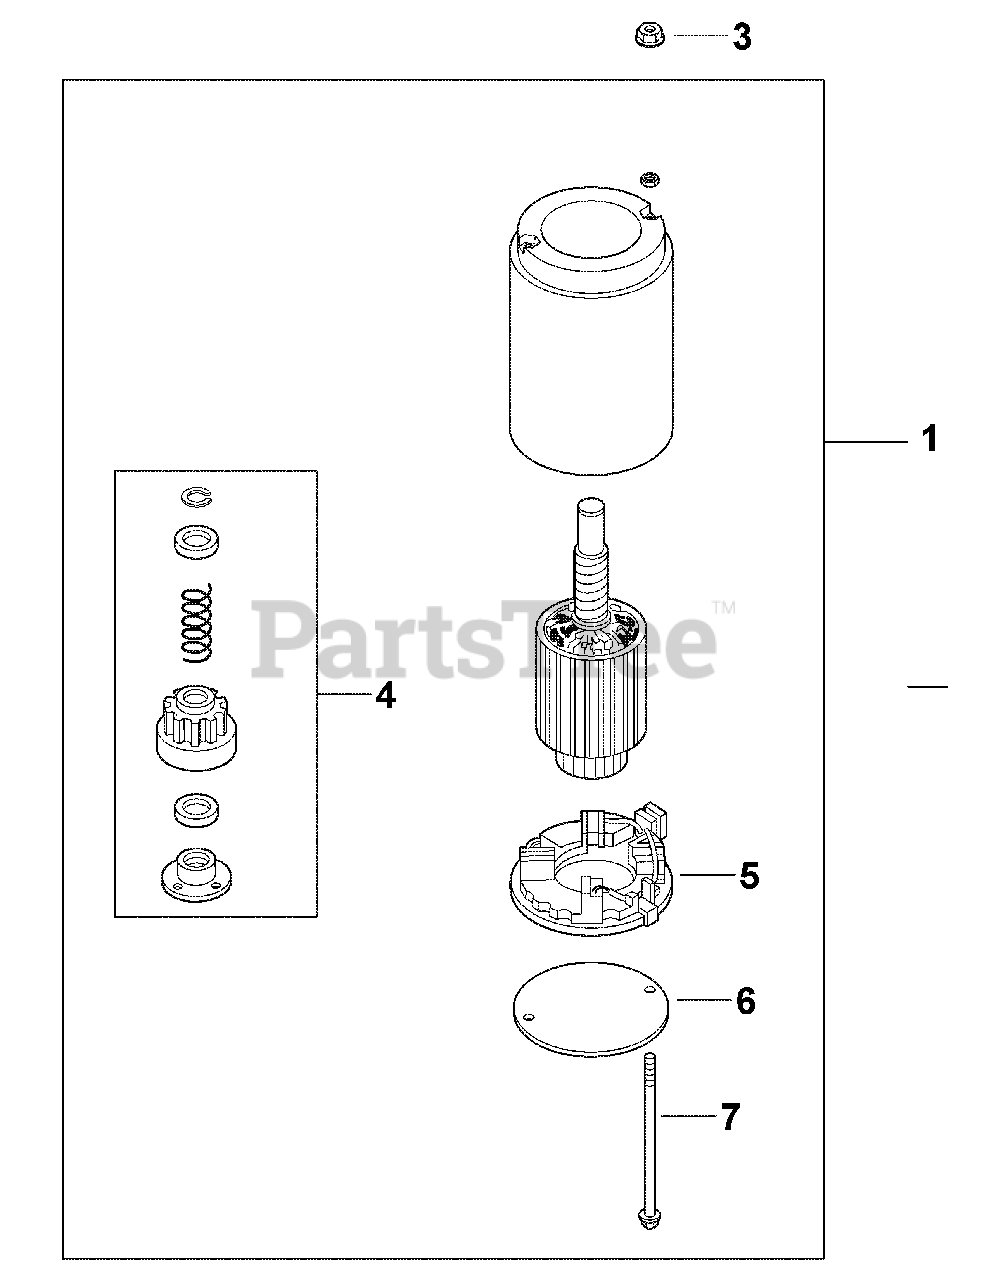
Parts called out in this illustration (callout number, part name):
1	Starter Assembly
3	Free Spinning Flg. Nut, #10-24
4	Drive Kit (J.E.)
6	Drive End Cap (J.E.)
